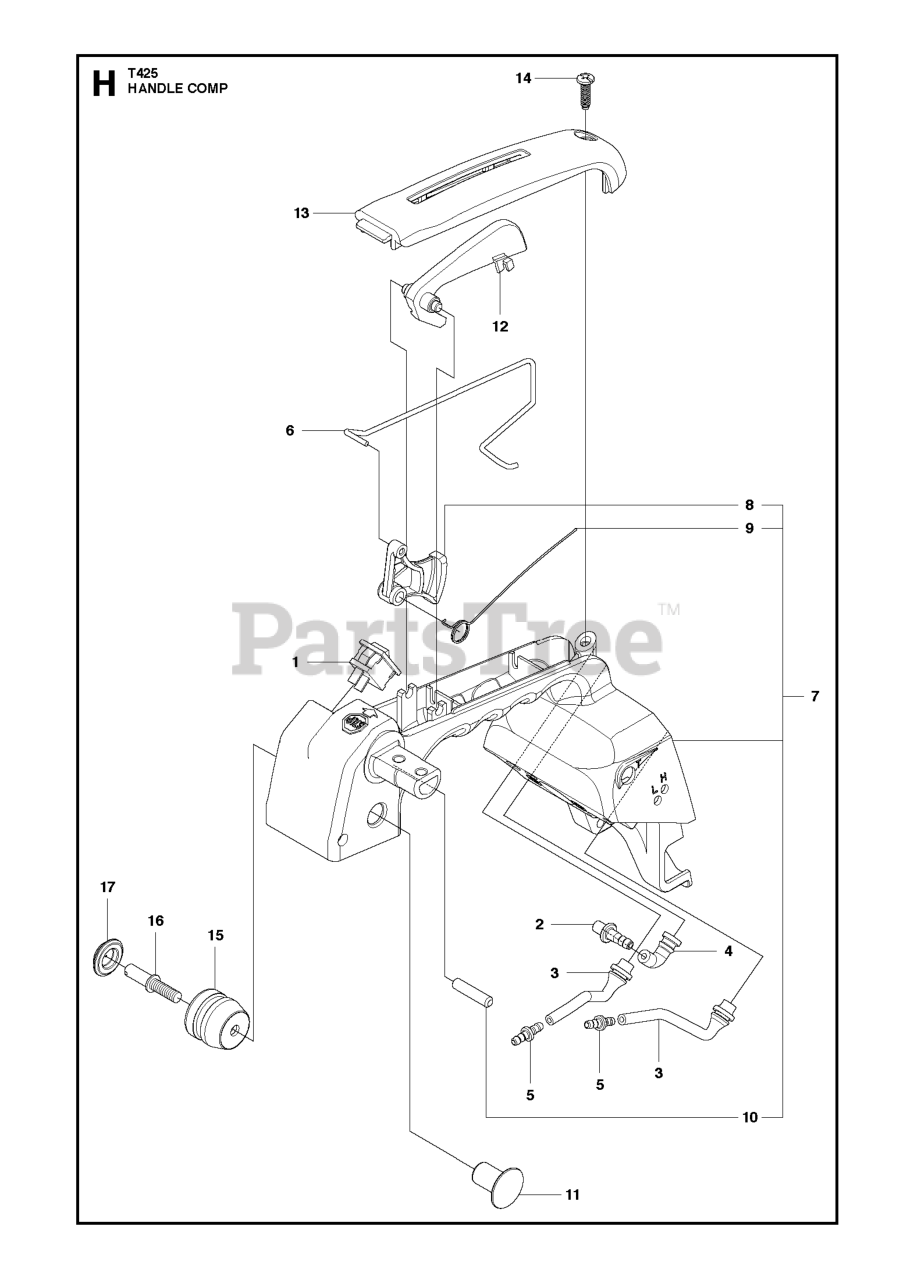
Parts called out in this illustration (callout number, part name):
2	ELBOW
5	RP JOINT
10	SPRING PIN
16	BOLT
